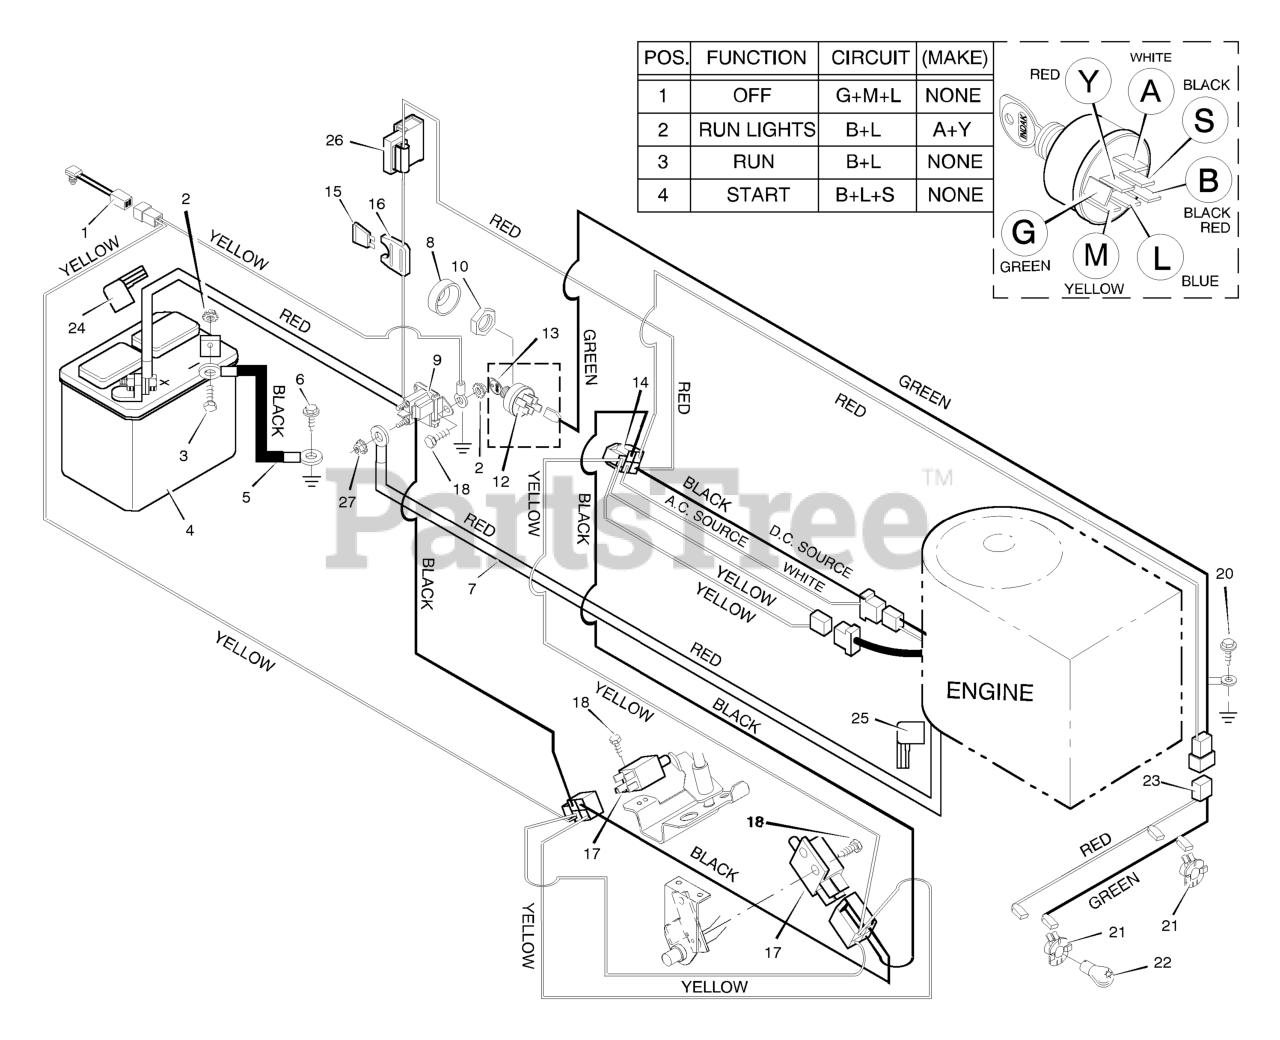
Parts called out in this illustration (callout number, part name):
1	Switch, Seat Sensor
2	Locknut
3	Bolt, Hex
4	Battery
5	Cable, Battery Ground
7	Cable, Red Battery
8	Cap, Ignition
9	Solenoid
10	Nut
12	Switch, Ignition
13	Key, Ignition
14	Harness, Chassis Wire
16	Holder, Fuse
17	Switch, Clutch
20	Screw
21	Socket, Light
22	Bulb, Light
23	Harness, Light Wire
24	Cover, Terminal
25	Cover,
26	Ammeter
27	Locknut
